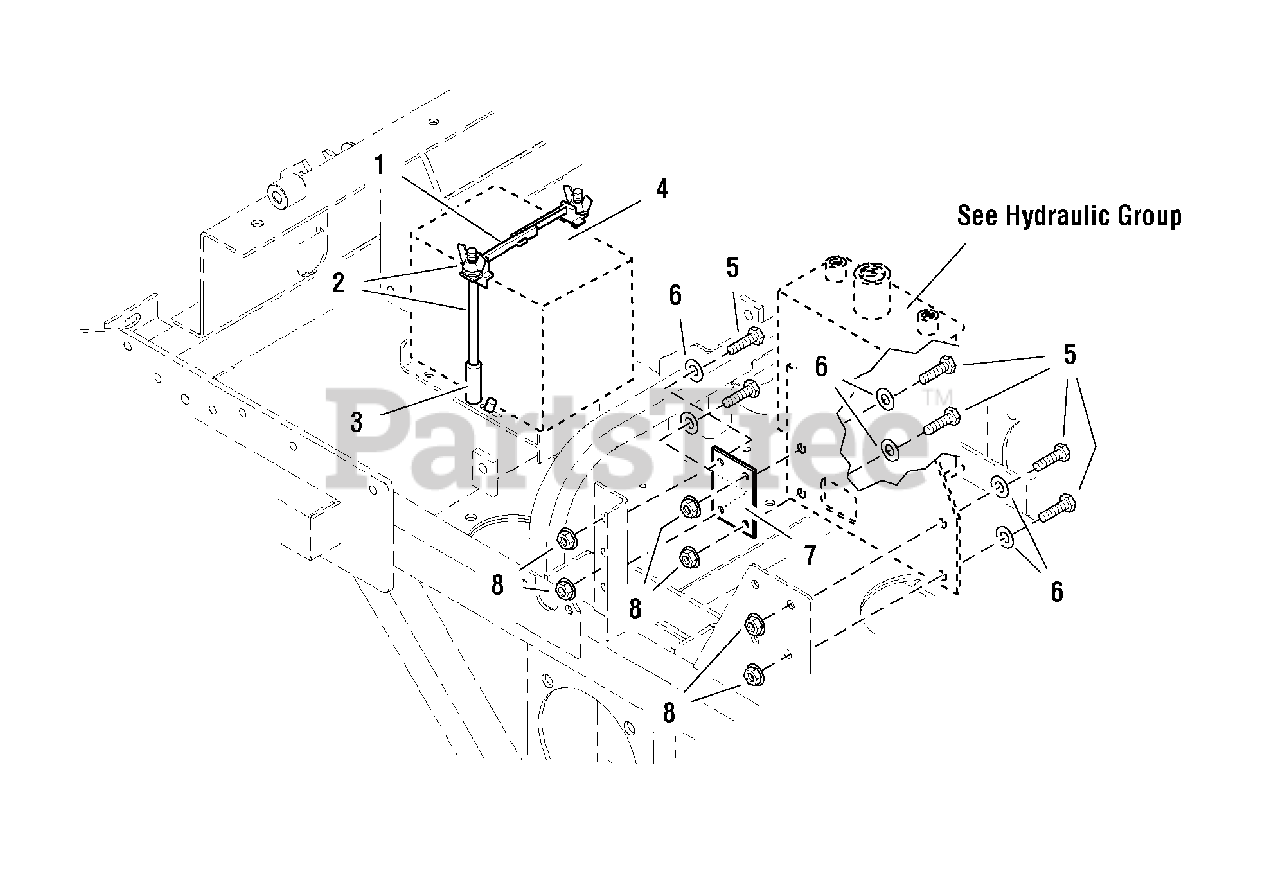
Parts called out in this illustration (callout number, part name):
1	BATTERY HOLDDOWN
2	BATTERY HOLDDOWN BOLT
4	BATTERY, 12V, 340 CCA Lawn & Garden
5	CAPSCREW, Hex Hd, 5/16-18 x 1
6	WASHER, 5/16
7	TANK MOUNT PLATE
8	NUT, Hex, Serrated Flange, 5/16-18
